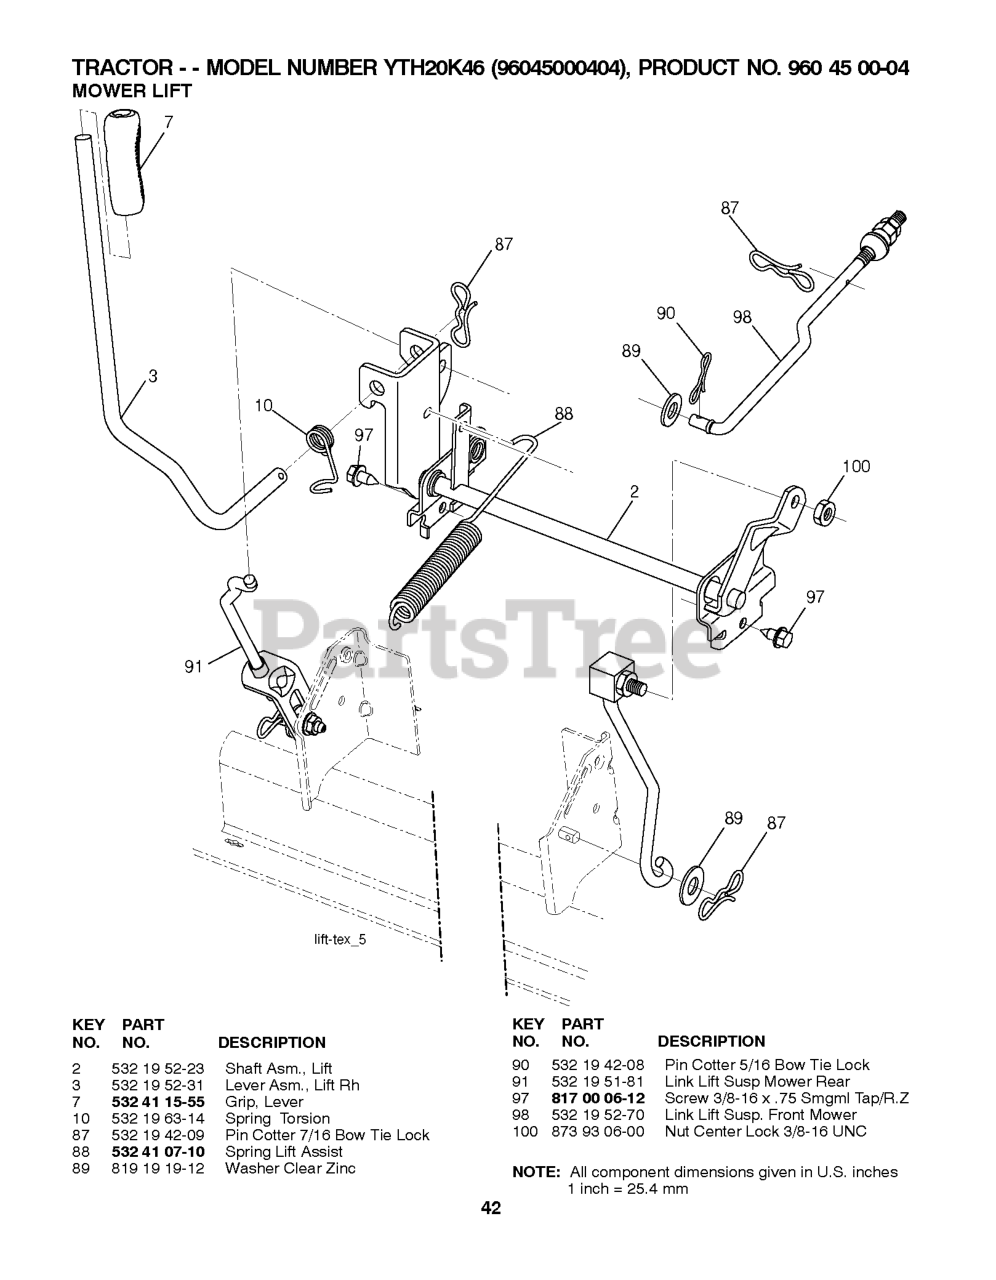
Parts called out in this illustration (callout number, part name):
2	SHAFT.ASM.LIFT.CROSS.H
3	LEVER.LIFT.HANDLE.LT
7	GRIP.HANDLE.LIFT.PVC.BLACK
10	SPRING.TORSION.LIFT.HANDLE
87	PIN.COTTER.7/16.BOW TI.
88	SPRING.LIFT.ASSIST
89	WASHER.CLEAR.ZINC
90	PIN.COTTER.5/16.BOW TI
91	LINK.ASM.LIFT.REAR
97	SCREW 3/8-16X3/4
98	LINK.ASM.SUSP.FRONT.MW
100	LOCKNUT
